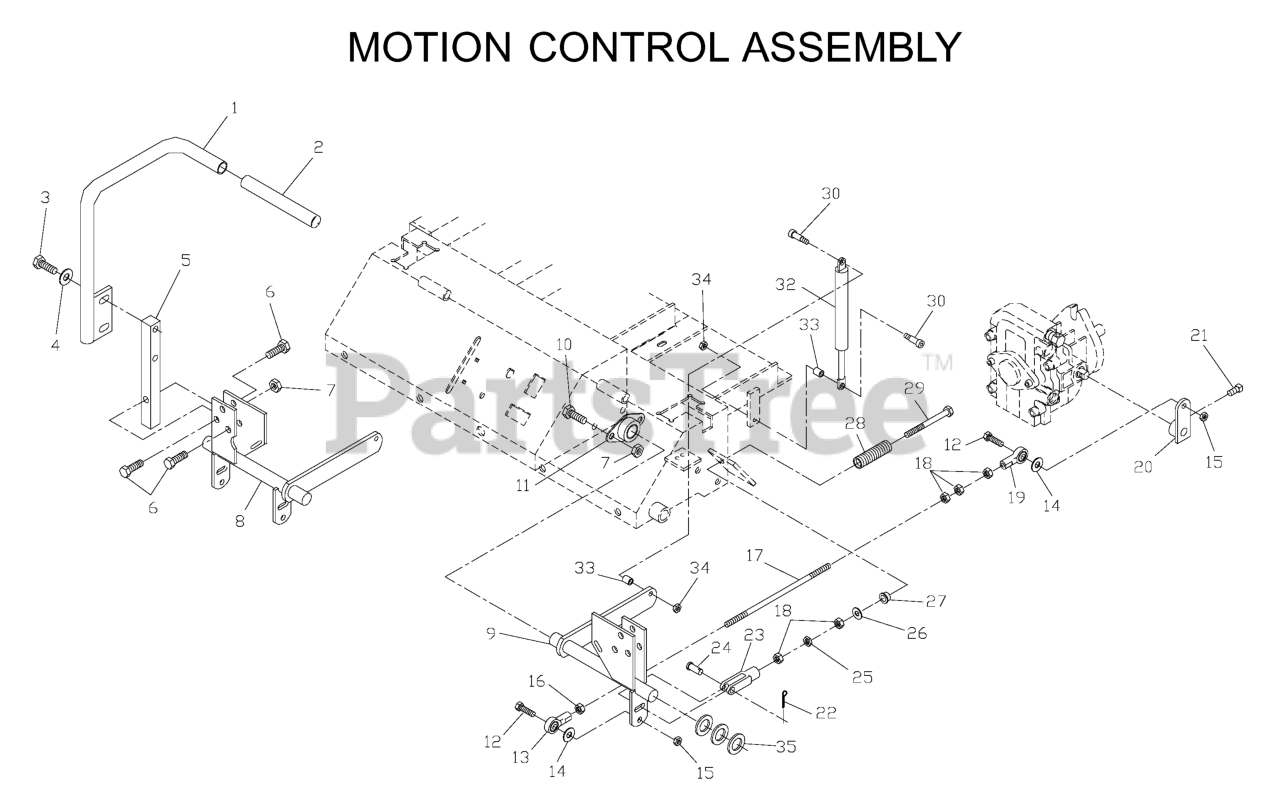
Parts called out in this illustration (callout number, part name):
1	MOTION CONTROL HANDLE, RIGHT
3	HCS 3/8-16X1.GRD.5.ZD
4	WASHER, 3/8 DISC SPRING SPEC
5	CONTROL ARM
6	HCS 3/8-16 X 1 3/4 GR5
7	NUT 3/8C CENTERBLOCK
8	BRACKET, RIGHT
9	BRACKET, LEFT
10	SCREW 3/8C X 3/4 HEX CAP
11	FLANGE BEARING
12	HCS 5/16C X 1 1/4
13	BALL JOINT, LEFT HANDED
14	WASHER 5/16 FLAT
15	NUT 5/16C CENTERLOCK
16	NUT 5/16F LEFTHAND
17	PUMP CONTROL LINK
19	BALL JOINT, RIGHT HANDED
20	PUMP CONTROL ARM
21	SCREW 5/16C X 5/8 SQ HEAD
22	COTTER PIN 3/32 X 1/2
23	YOKE 5/16 ADJ CLEVIS
24	CLEVIS PIN 5/16 X 1
25	NUT JAM 5/16F HEX
26	WASHER 1/4 FLAT
27	BUSHING, NYLON
29	SCREW, NEUTRAL RETURN SHOULDER
30	SCREW, 5/16 X 5/8 SHOULDER
34	NUT 1/4C CENTERLOCK
35	BUSHING, MACH
539102585	MOTION CONTROL HANDLE, LEFT
